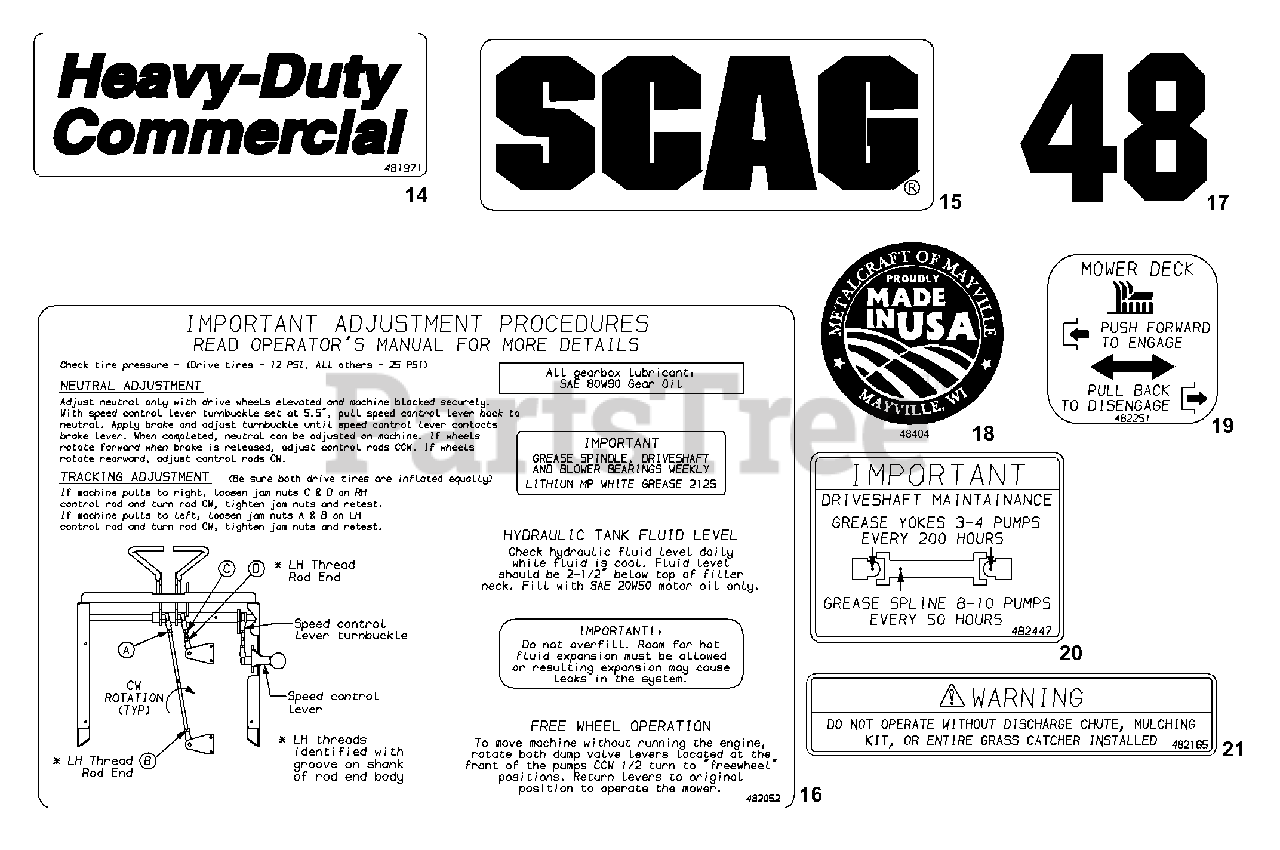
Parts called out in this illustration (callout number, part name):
14	Decal, Heavy Duty
15	Decal, SCAG
16	Decal, Adjustments
17	Decal, 42" Cutter Deck
18	Decal, Made in the USA - Metalcraft of Mayville, Inc.
19	Decal, PTO Engagement
20	Decal, Driveshaft Grease
21	Decal, Warning
